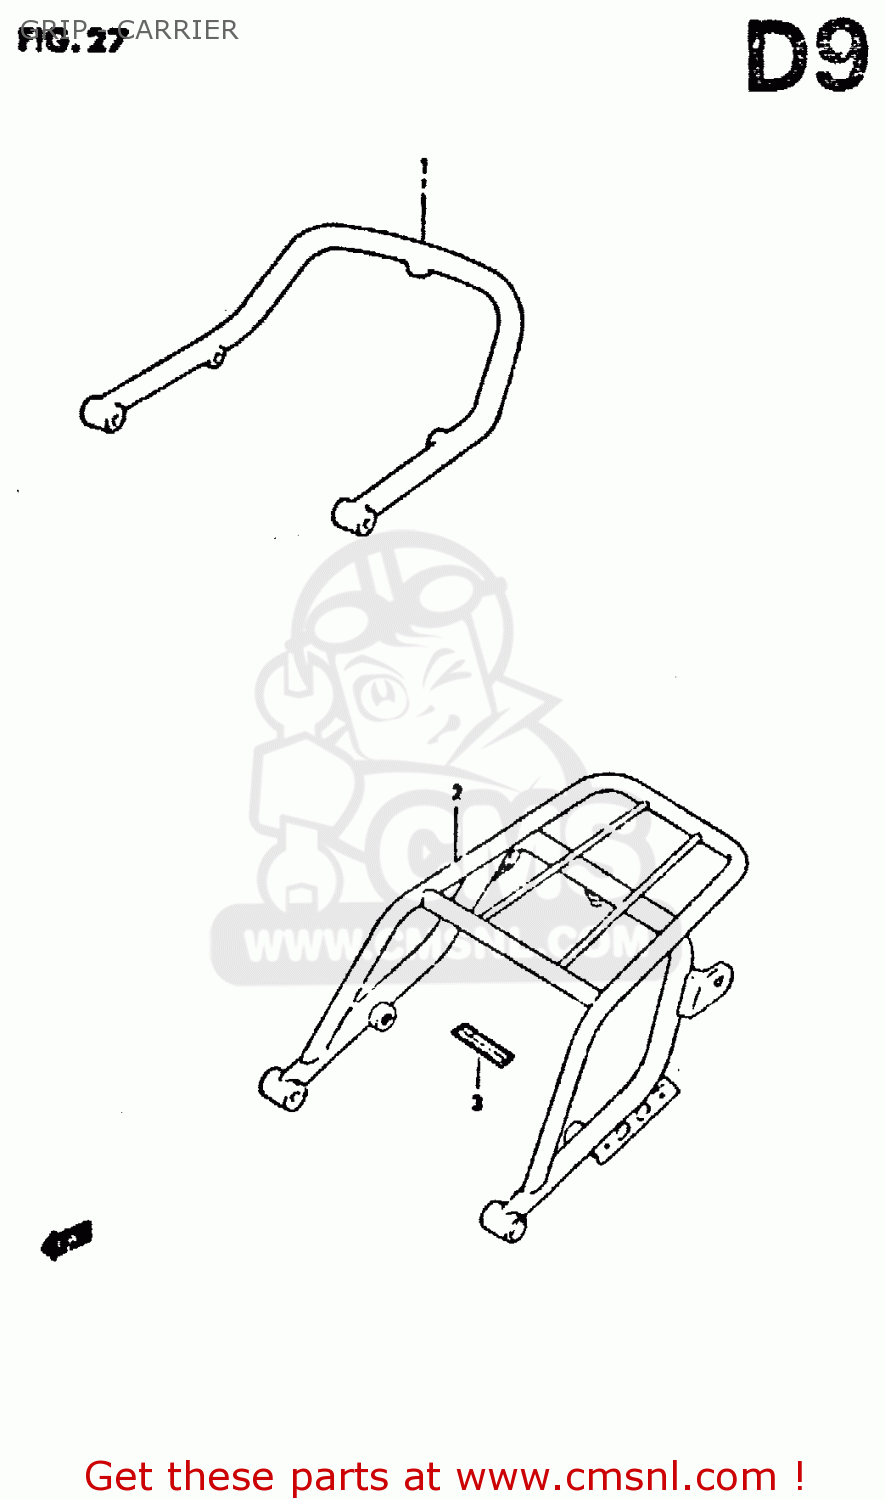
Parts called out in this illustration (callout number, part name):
1	GRIP,RR
2	CARRIER,SPORT
3	LABEL,WARNING
